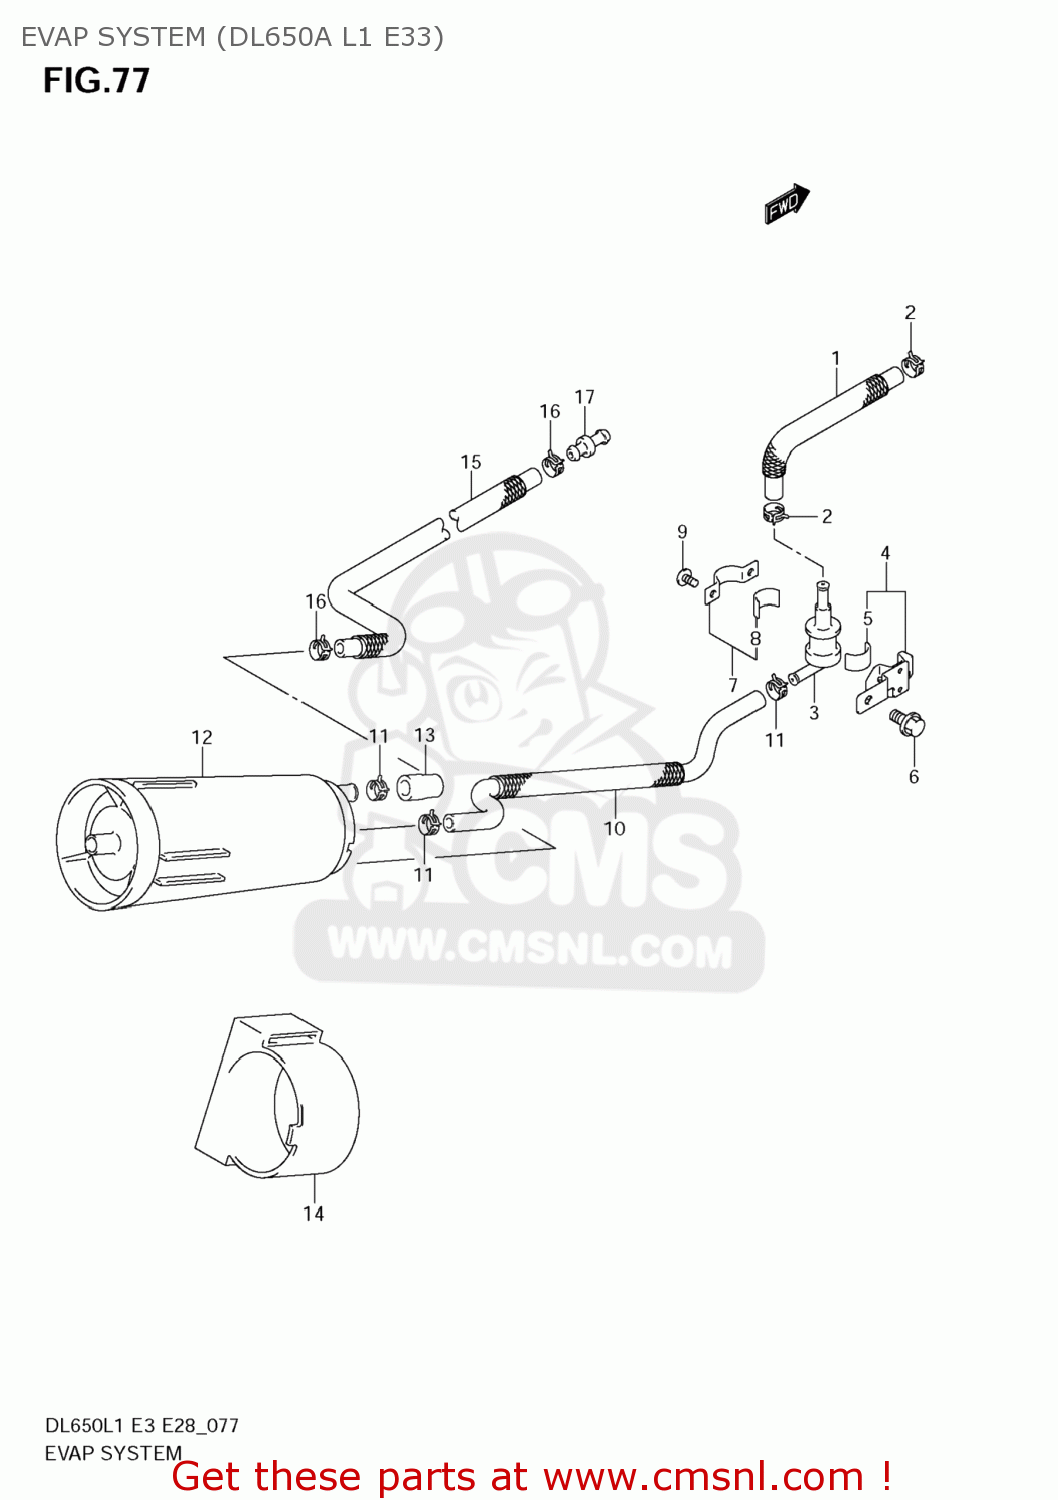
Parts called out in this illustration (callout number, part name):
1	HOSE,TANK & BREATHER VALVE
2	CLIP
3	VALVE,FUEL TANK BREATHER
4	PLATE,BREATHER VALVE
5	CUSHION
6	BOLT
7	PLATE,FUEL TANK BREATHER NO.2
8	CUSHION
9	SCREW
10	HOSE,BREATHER VALVE & CANISTER
11	CLIP
12	CANISTER ASSY,CHARCOAL
13	CAP
14	CUSHION,CANISTER
15	HOSE,CSTR PURGE
16	CLIP
17	JOINT
